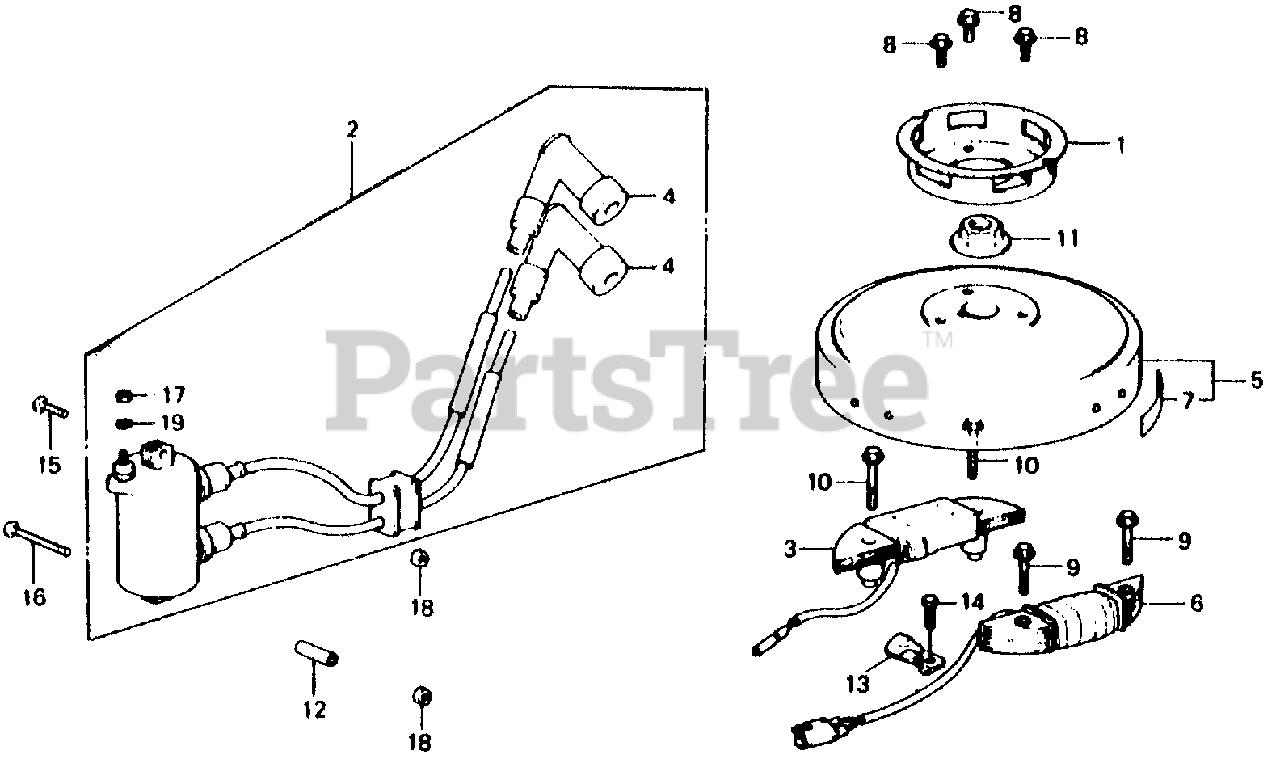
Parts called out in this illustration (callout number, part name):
1	PULLEY, STARTER
2	COIL ASSY., C.D.I. IGNITION
3	COIL ASSY., EXCITER
4	CAP ASSY., NOISE SUPPRESSOR
5	FLYWHEEL *NH1* (BLACK)
6	COIL ASSY., CHARGE (NOT AVAILABLE)
7	MARK, FLYWHEEL CAUTION
8	BOLT, FLANGE (6X12)
9	BOLT, FLANGE (6X28)
10	BOLT, FLANGE (6X35)
11	NUT, SPECIAL (14MM)
12	COLLAR, DISTANCE
13	CLIP, WIRE
14	BOLT, HEX. (6X12)
15	SCREW, PAN (6X25)
16	SCREW, PAN (6X50)
17	NUT, HEX. (5MM)
18	NUT, HEX. (6MM)
19	WASHER, SPRING (5MM)
